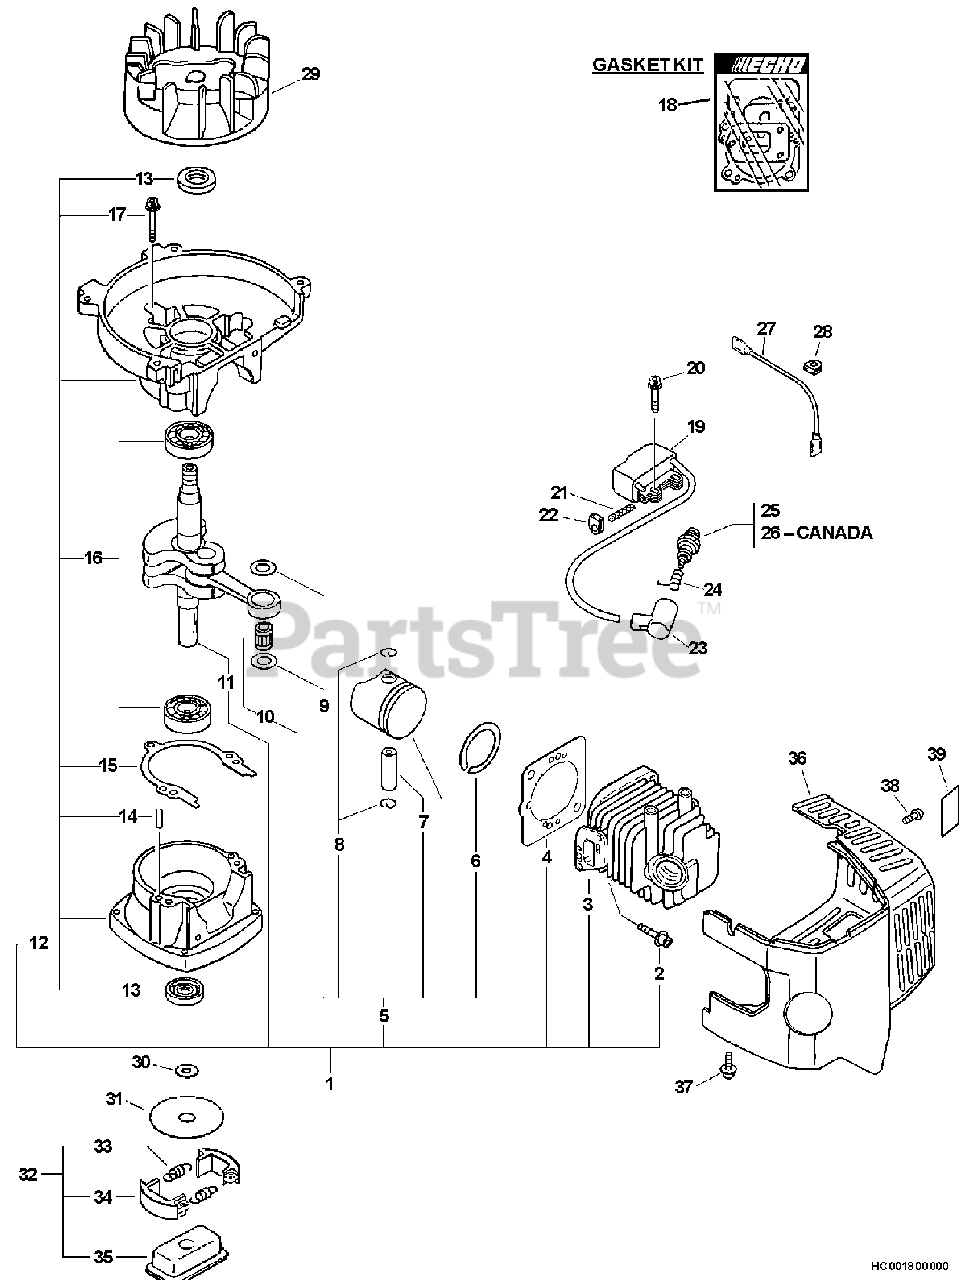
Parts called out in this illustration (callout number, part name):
1	SHORT BLOCK -- SB1074
2	SCREW - 5X22
3	CYLINDER
4	GASKET, CYLINDER
5	PISTON KIT
6	RING, PISTON
7	PIN, PISTON
8	RING, RETAINING
10	BEARING, NEEDLE - 8
11	CRANKSHAFT ASSY
12	CRANKCASE KIT
13	SEAL, OIL
14	PIN - LOCATING
15	GASKET, CRANKCASE
16	BEARING, BALL - 6201
17	SCREW - 5X28
18	GASKET KIT
19	COIL, IGNITION
20	SCREW - 4X20
21	TUBE, INSULATOR
23	CAP, SPARK PLUG
24	TERMINAL, SPARK PLUG CAP
25	SPARK PLUG -- BPM-8Y
26	SPARK PLUG -- BPMR-8Y
27	LEAD - IGNITION
29	FLYWHEEL
30	WASHER, CLUTCH
31	PLATE, CLUTCH
32	CLUTCH ASSY
33	SPRING, CLUTCH
34	SHOE, CLUTCH
35	HUB, CLUTCH
36	COVER, ENGINE - GRAY
37	SCREW - 4X20
38	SCREW - 4X8
39	LABEL - HOT SURFACE
